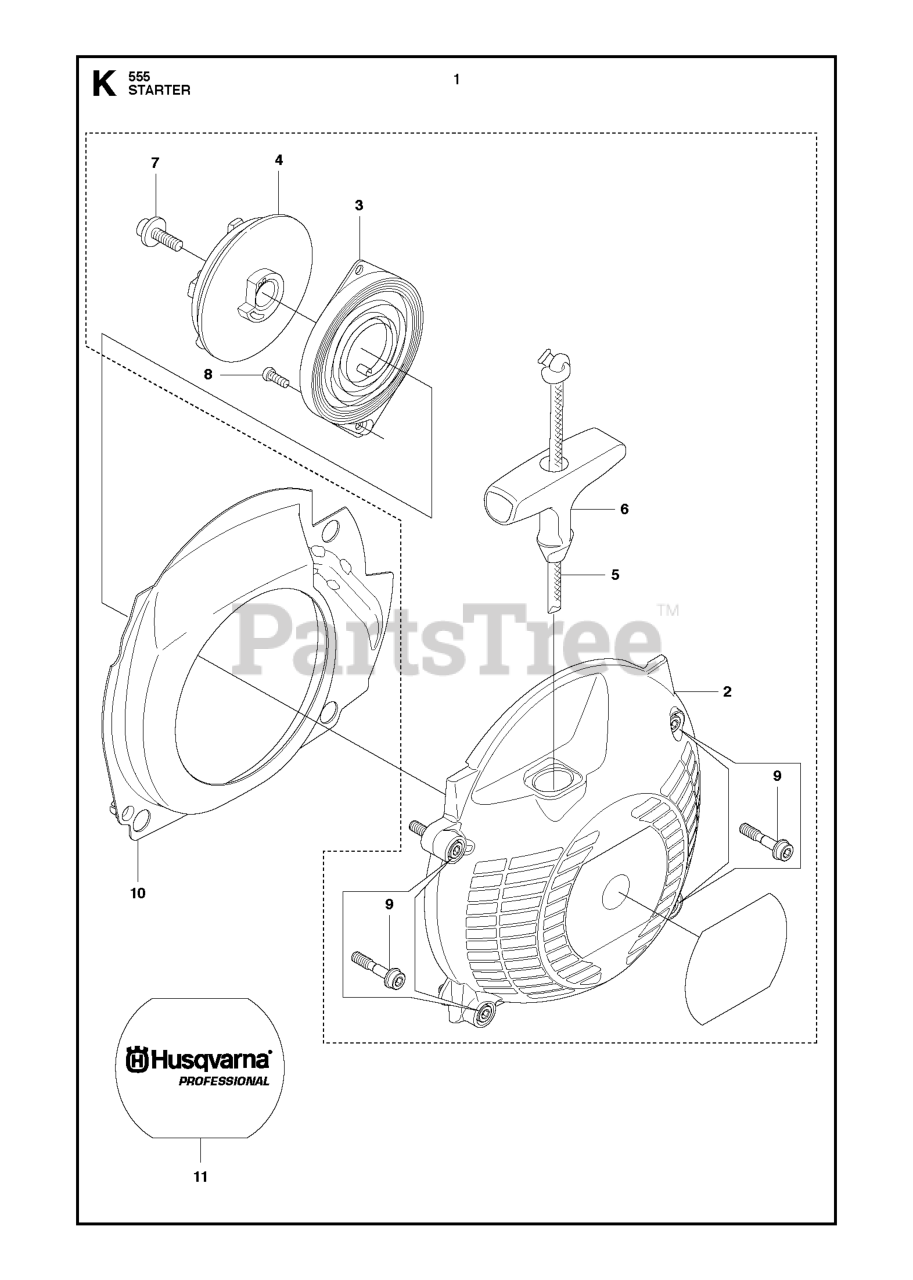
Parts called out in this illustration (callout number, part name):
1	STARTER ASSY
2	STARTER HOUSING SPARE PART IN
3	RECOIL SPRING
4	STARTER PULLEY
5	STARTER ROPE
9	SCREW IHSCFMO
10	AIR CONDUCTOR
